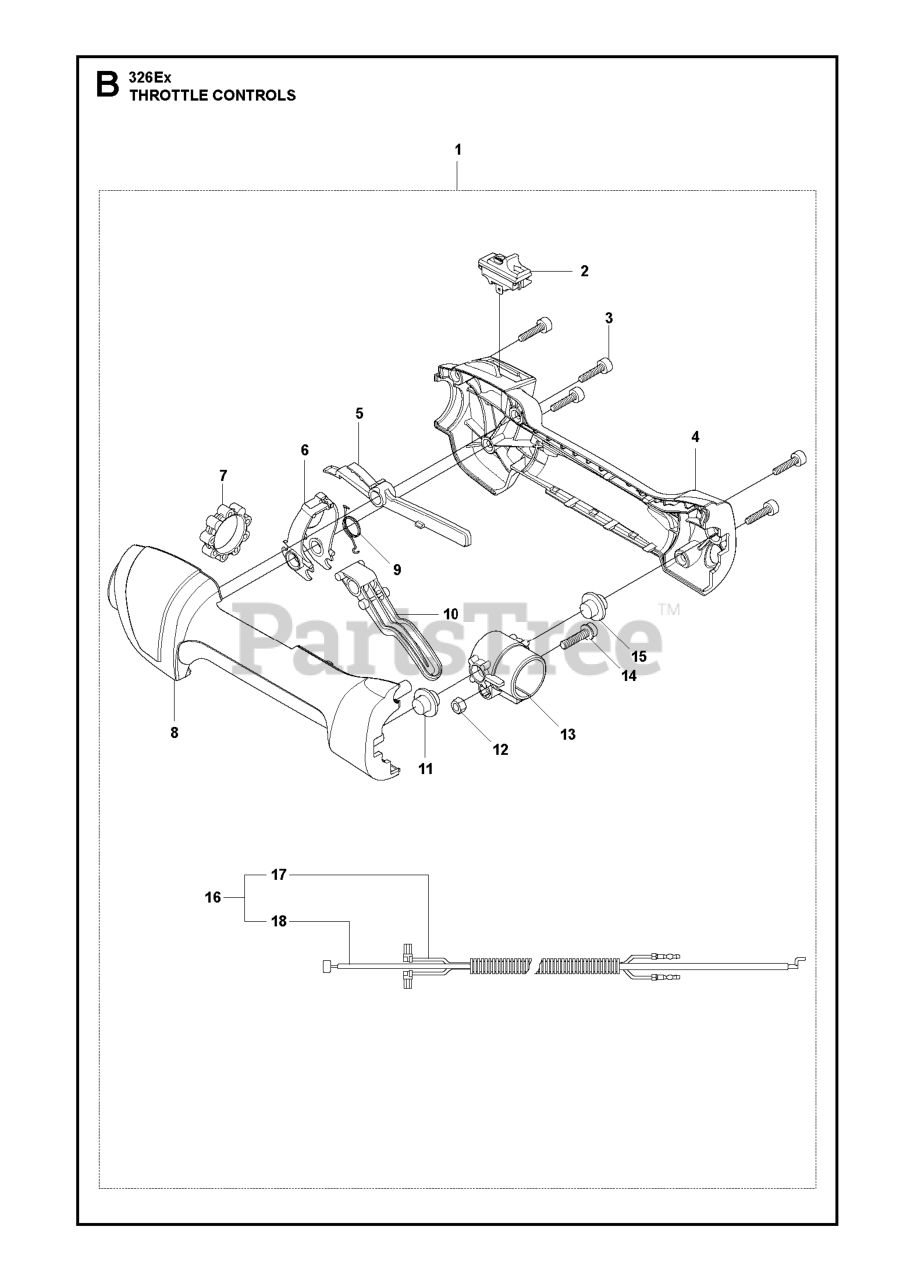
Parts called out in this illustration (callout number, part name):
1	ASSY THROTTLE CONTROL
2	STOP BUTTON
5	THROTTLE LOCK
7	VIBRATION DAMPER
9	RETURN SPRING
10	THROTTLE TRIGGER
11	VIBRATION ABSORBER
15	VIBRATION ABSORBER
17	SHORT CIRCUIT CABLE
18	THROTTLE WIRE ASSY
